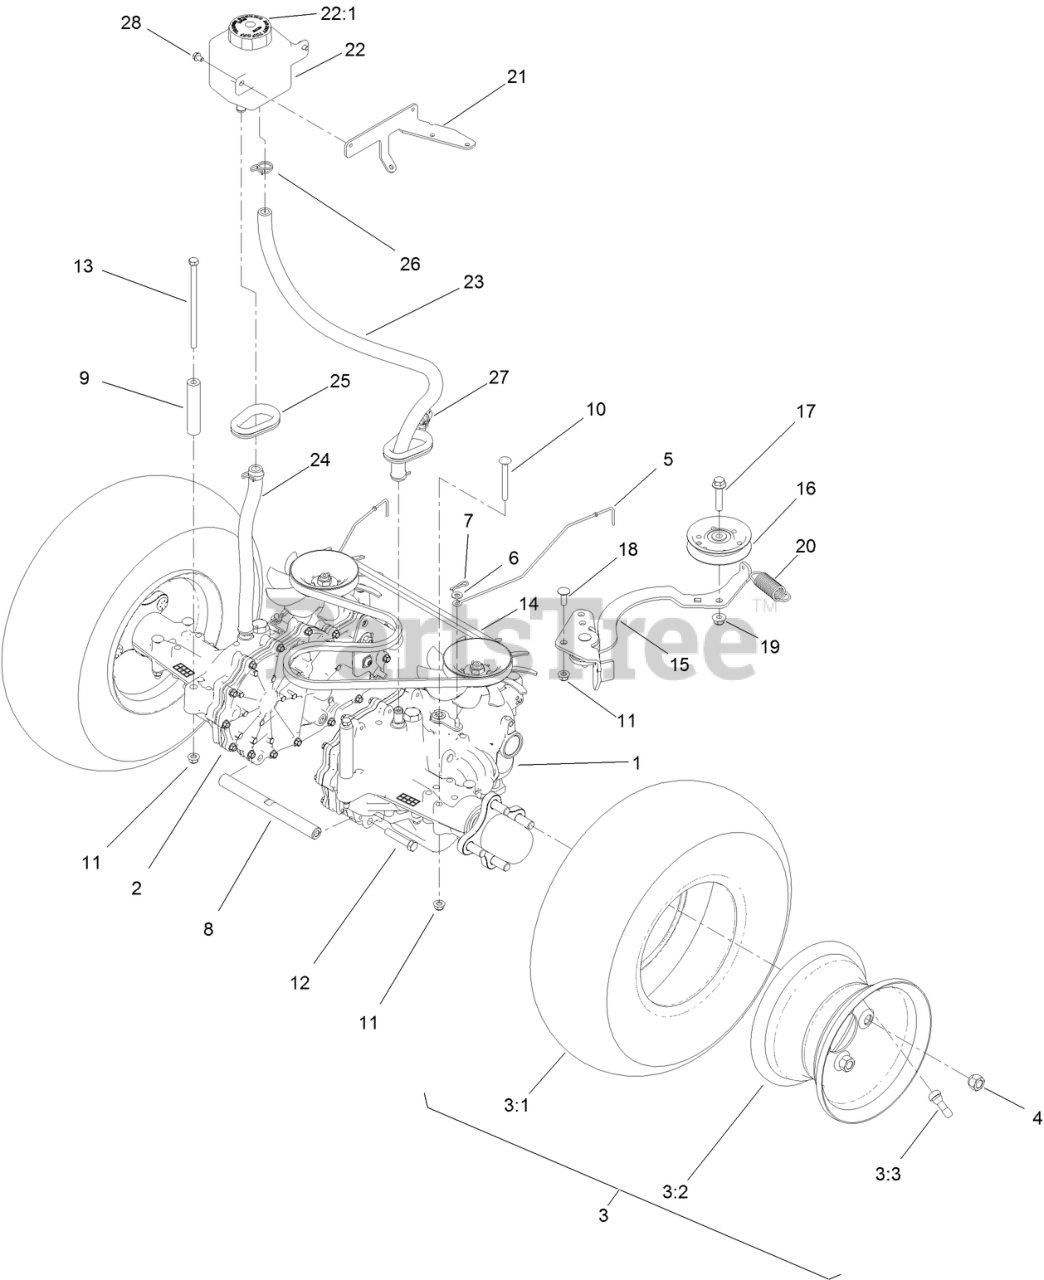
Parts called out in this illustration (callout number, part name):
1	TRANSMISSION, ZT-2800 LH
2	TRANSMISSION, ZT-2800 RH
3	WHEEL AND TIRE ASM
3:1	TIRE-4 PLY
3:2	RIM-8"
4	NUT-LUG
5	ROD-BYPASS
6	WASHER-FLAT
7	PIN-COTTER
8	SHAFT-CROSS, HYDRO
9	SPACER - TRANSMISSION
10	SCREW-CARR
11	NUT-HF, NI
12	SCREW-HH W/LOCTITE
13	SCREW-HH
14	BELT-V
15	IDLER ARM PIVOT ASM
16	PULLEY-IDLER, FLAT
17	SCREW-HHF
18	BOLT-CARR
19	NUT-HF, NI
20	SPRING-EXTENSION
21	BRACKET - EXPANSION TANK
22	TANK-HYD
22:1	CAP-RESERVOIR, HYD
23	HOSE-OVERFLOW
24	HOSE-OVERFLOW
25	GROMMET
26	CLAMP-HOSE
27	CLIP-TIE
28	SCREW-HWH
